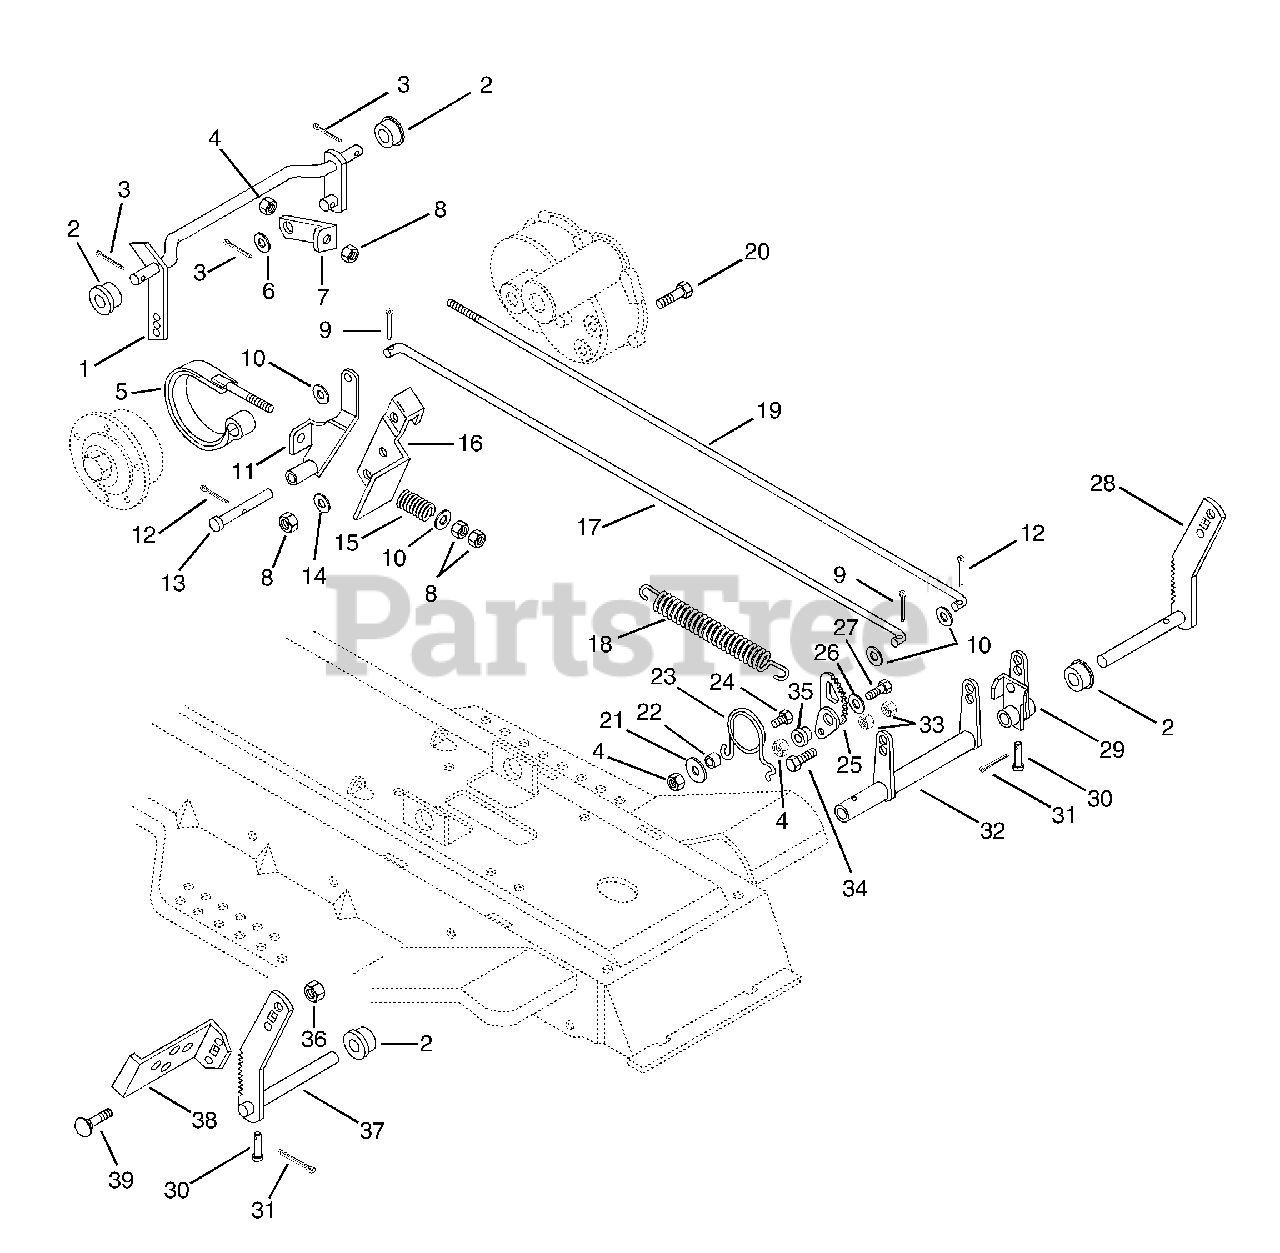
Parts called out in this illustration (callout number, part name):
1	CLUTCH SHAFT
2	FLANGE BUSHING
3	@PIN-CTR .12X1.00 EXTPRSQCT YZ
4	@NUT-LK-CTR .31-18 YWZC
5	BRAKE BAND
6	WSHR-FL-STL .520X.810X.033YWZC
7	CLUTCH BRACKET
8	@NUT-HEX .31-18 YWZC
9	@PIN-CTR .09X.75 EXTPRSQCT YWZ
10	WSHR-FL-STL .323X.625X.062 YWZ
11	BRAKE LEVER
12	@PIN-CTR .12X.75 EXTPRSQCT YWZ
13	PIN-CLEV .371X3.25
14	WSHR-LK-INT .313X.030 PL
15	SG-COMP .105X.585X.75
16	BRAKE BRACKET
17	BRAKE ROD
18	SG-TENS .051X.60X2.25 WLD 7.0
19	ROD, CLUTCH
20	BLT-SERRDHD SL .31-18X.75 YZ
21	WSHR-FL-STL .328X.875X.062YWZC
22	SPACER BUSHING .5 X .32 X .163
23	SG-TORS .125X1.0X1.75
24	@BLT-HEX .31-18X.75 GR5 YWZC
25	BRAKE LATCH
26	@WSHR-FL-STL.38X.875X.083 YWZC
27	@BLT-HEX .31-18X1.00 GR5 YWZC
28	CLUTCH PEDAL ARM
29	CLUTCH ARM
30	PIN-CLEV .185X1.00 SP
31	PIN-COTR .06X.50
32	BRAKE ARM
33	@NUT-HEX 8-32 YWZC
34	SCR-MCH 8-32X1.00 HWH YWZC
35	SPACER -SHLD .344X.500X.469
36	@NUT-LK-CTR-JAM .375-16 YWZC
37	BRAKE PEDAL ARM
39	BLT-RHHDSQSHNK .38-16X.75 G2YZ
